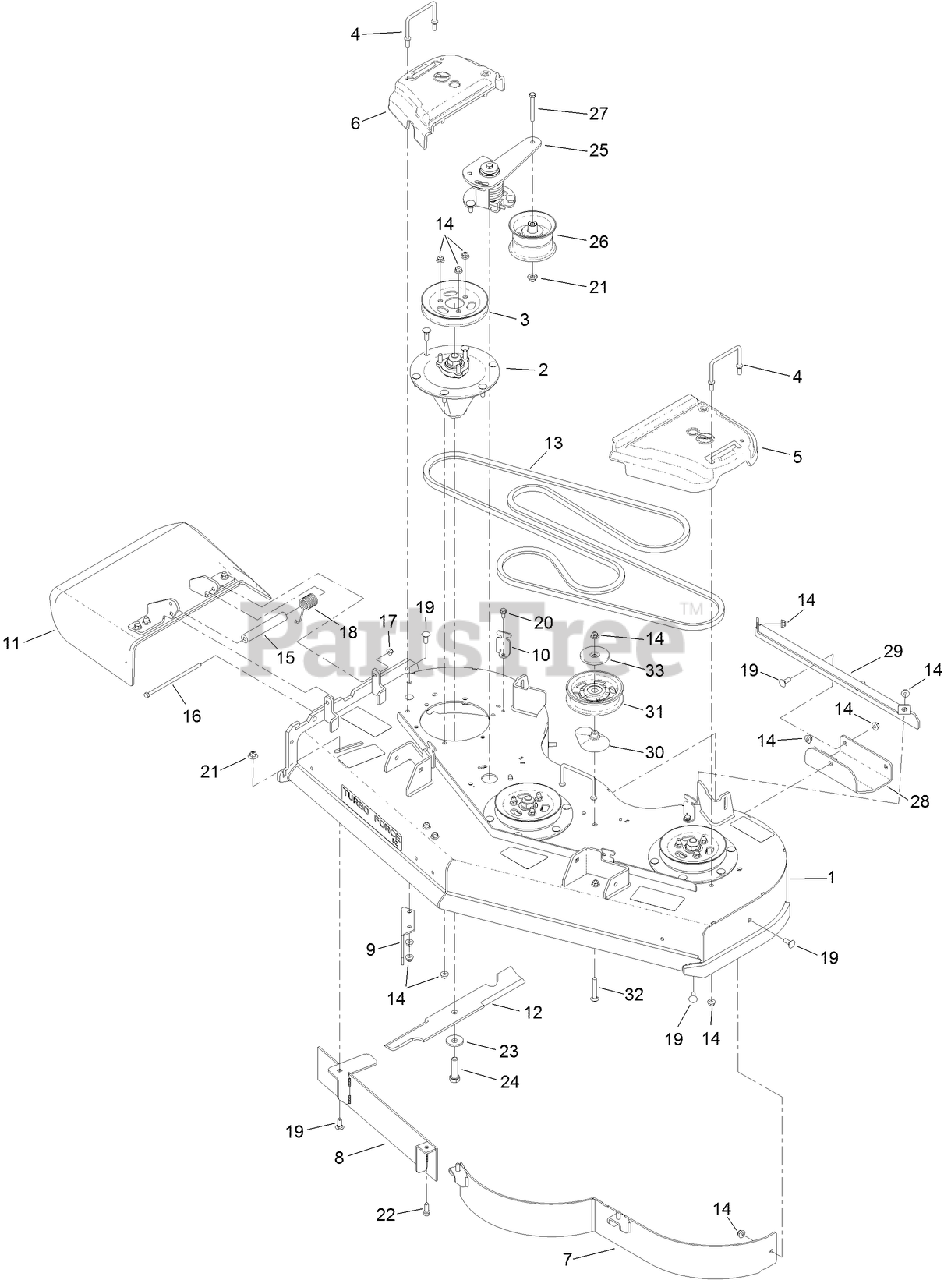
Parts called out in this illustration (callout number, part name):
1	DECK ASM
2	SPINDLE ASM
3	PULLEY
4	WIREFORM-COVER
5	COVER-BELT, LH
6	COVER-BELT, RH
7	BAFFLE-52 INCH
9	BAFFLE-DISCHARGE
10	BRACKET-COVER
11	DEFLECTOR ASM
12	BLADE-18IN, HI FLOW
13	BELT-V
14	NUT-HF, NI
15	SPACER
16	SCREW-HH
17	NUT-HF, NI
18	SPRING-TORSION
19	BOLT-CARR
20	SCREW-HWHTF
21	NUT-FLANGE, NI
22	SCREW-HWH
23	Washer-Blade Bolt, Heavy
24	SCREW-BLADE
25	TORSION IDLER ASM
26	PULLEY-IDLER
27	SCREW-HH
29	BRACKET-SKID
30	SPACER-PULLEY
31	IDLER-PULLEY, FLAT
32	SCREW-CARR
33	SHIELD-DUST
